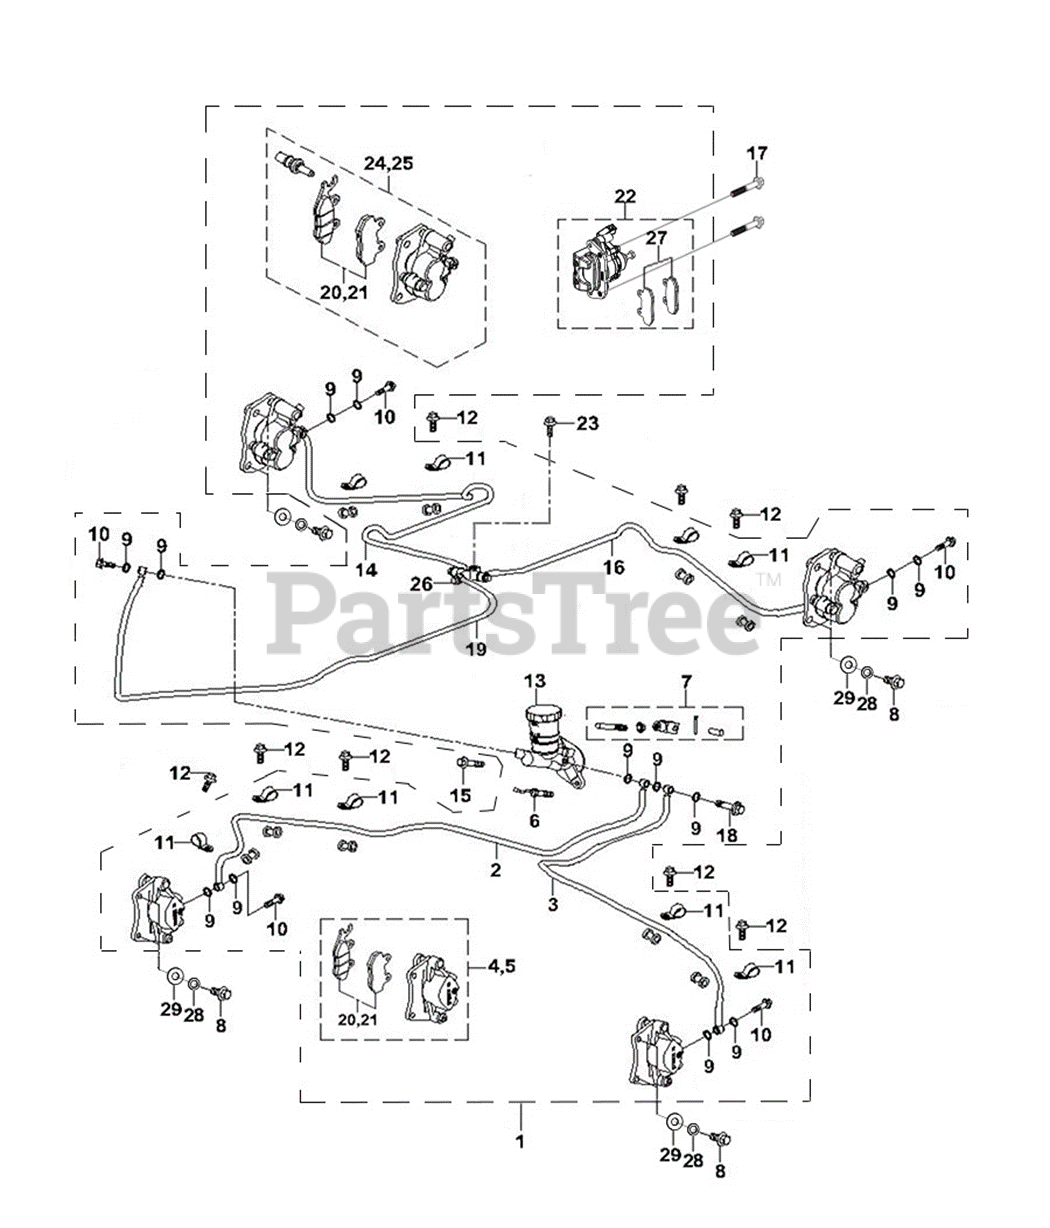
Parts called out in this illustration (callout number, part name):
1	BRAKE SYSTEM ASSEMBLY
2	BRAKE LINE - FRONT RIGHT
3	BRAKE LINE - FRONT LEFT
4	DISC BRAKE CALIPER ASM FRONT RIGHT
5	DISC BRAKE CALIPER ASM FRONT LEFT
6	TAIL LIGHT BRAKE SWITCH
7	BRAKE ROD ASSEMBLY
8	HEX FLANGE BOLT (M10x1.25x28)
9	HYDRAULIC OIL PIPEWASHER
10	HYDRAULIC OIL PIPEBOLT I
11	OIL PIPE CLAMP
12	HEXAGON FLANGE BOLT M6X16
13	MAIN BRAKE PUMP ASSEMBLY
14	BRAKE LINE (REAR RH)
15	FLANGE BOLT M8X25
16	BRAKE LINE - REAR LEFT
17	HEX HEAD FLANGE BOLT M10X1.25-40
18	BANJO BOLT II
19	BRAKE LINE - MIDDLE
20	FRONT LEFT BRAKE PAD ASSEMBLY
21	FRONT RIGHT BRAKE PAD ASSEMBLY
22	PARKING BRAKE ASSEMBLY
23	HEXAGON FLANGE BOLT M6X35
24	DISC BRAKE CALIPER ASM REAR RIGHT
25	DISC BRAKE CALIPER REAR LEFT
27	PARKING BRAKE PAD SET
28	SPRING WASHER
